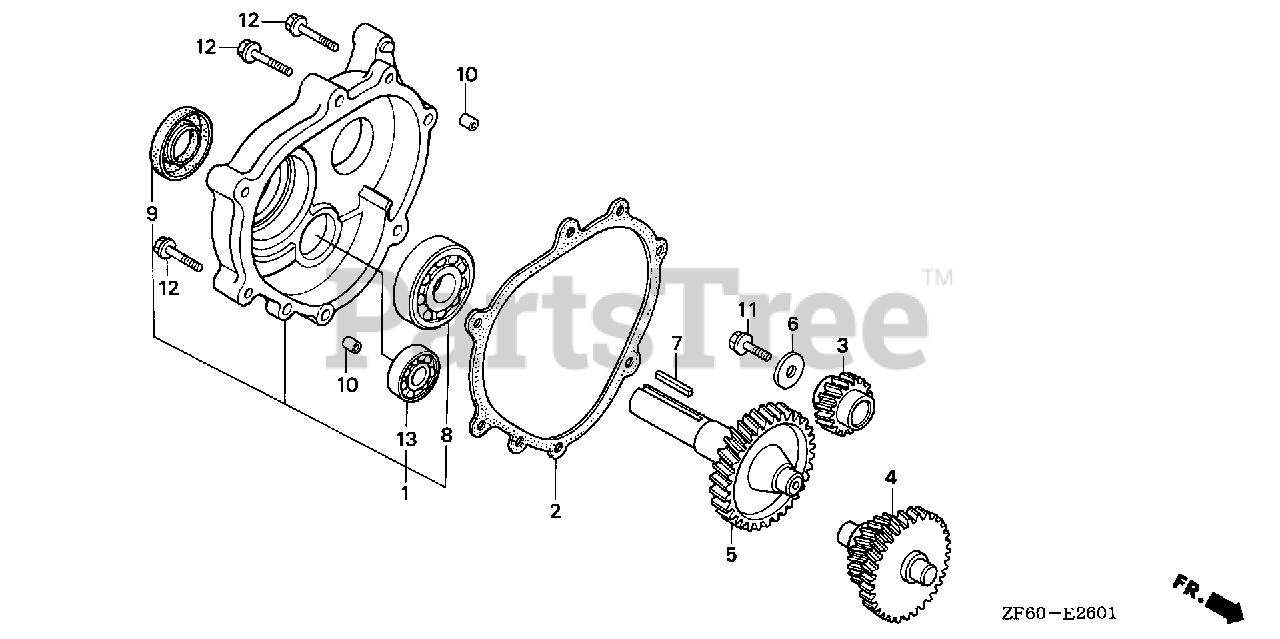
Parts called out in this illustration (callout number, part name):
1	COVER ASSY., GEAR CASE
2	GASKET, CHAIN CASE COVER
3	GEAR, PRIMARY DRIVE (12T)
4	COUNTERSHAFT (13T/27T)
5	SHAFT, P.T.O. (34T)
6	WASHER (8MM)
7	KEY (6.3X6.3X43)
8	BEARING, RADIAL BALL (6206) (NTN)
9	OIL SEAL (30X46X8)
10	PIN, DOWEL (8X14)
11	BOLT, FLANGE (8X25)
12	BOLT, FLANGE (8X40)
13	BEARING, RADIAL BALL (6302)
